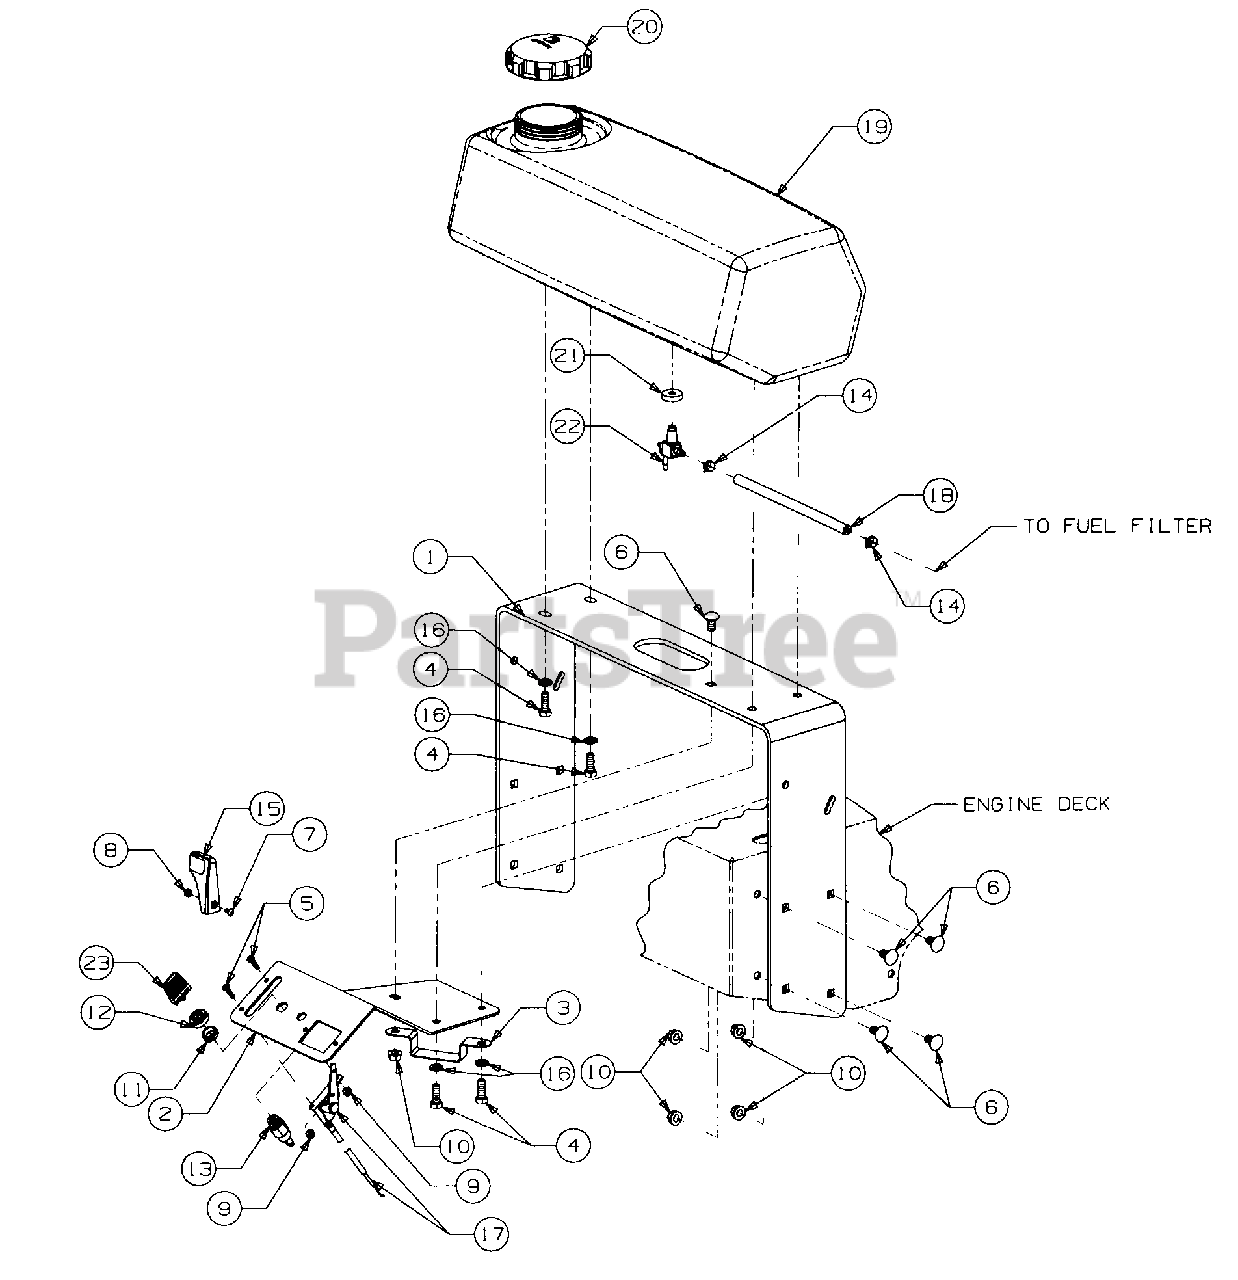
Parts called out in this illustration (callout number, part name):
1	Support, Lower Handle
2	Panel w/Graphic, Control (Kohler engine)
3	Bracket, Cable Retainer
4	Screw, Hex Cap, 3/8-16 X 1.0 Lg GR5
5	Screw, Pan Hd Cutting, #10-24 X .75 Lg
6	Bolt Sht Nk Carriage, 3/8-16 X .75 Lg GR5
7	Screw, Cross Rec Truss Hd, #8-32 X .38 Lg
8	Nut, Hex,#8-32
9	Nut, Hex Nylock, #10-24
10	Nut, Hex Flanged Lock, 3/8-16
11	Nut, Ignition Switch, 5/8-32
12	Cap, Ignition Switch
13	Switch, Ignition
14	Clamp, Hose
15	Knob, Throttle Control
16	Washer, Lock, 3/8
17	Control, Throttle
18	Line, Fuel - 9" Lg - Order bulk fuel line part no. 759-3330, 10 ft Lg
19	Tank, Fuel (Includes Ref No. 218 22)
20	Cap, Fuel
21	Grommet, Shutoff Valve
22	Valve, Fuel Shutoff
23	Key, Ignition (Set of 2)
